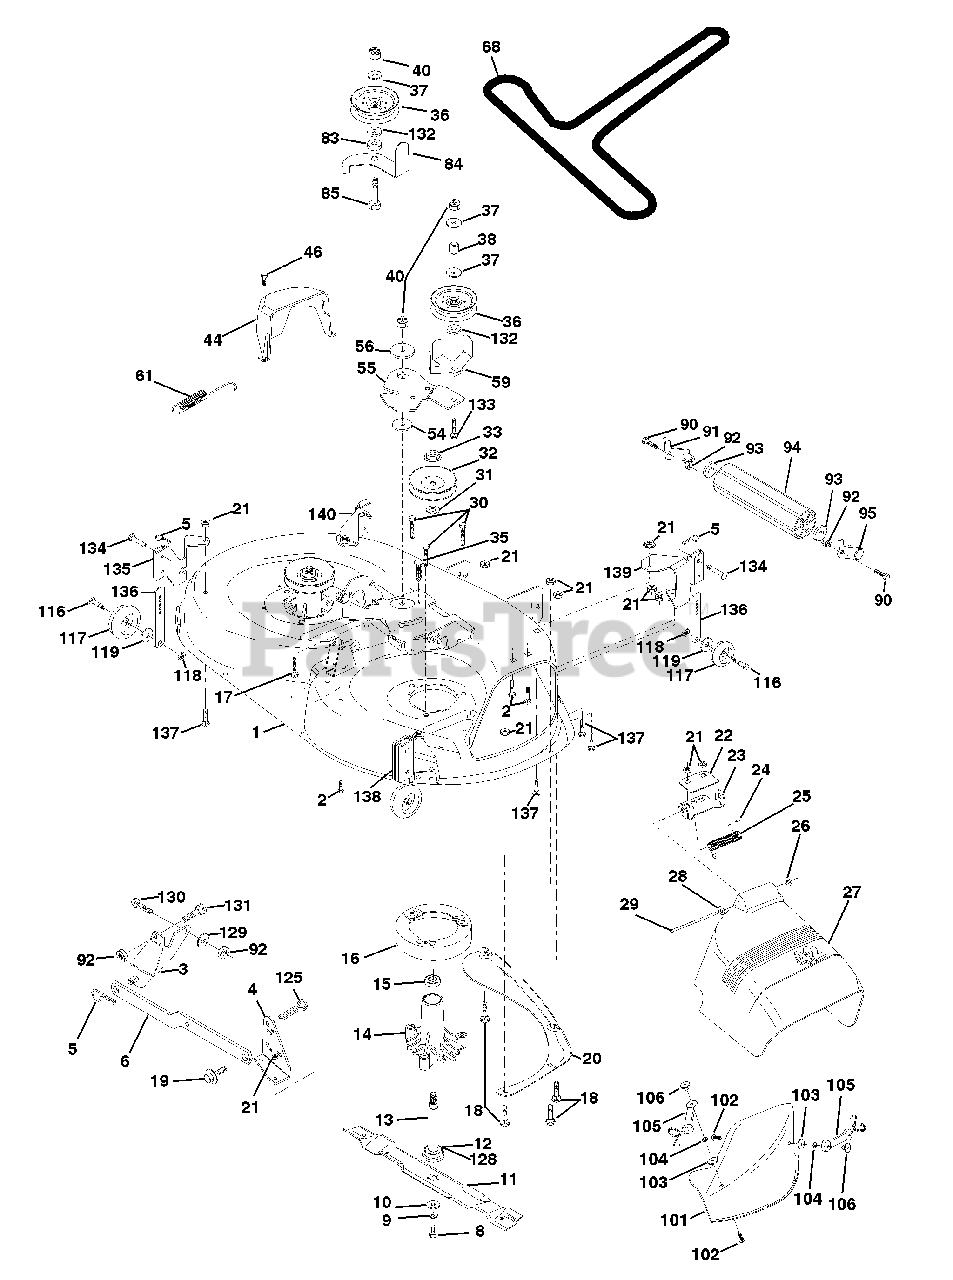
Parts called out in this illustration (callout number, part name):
1	Deck Weldment Mower
2	Bolt Rdhd Sqnk 5/16-18unc X3/4
3	Bracket Asm Fr Sway Bar 38/42
4	Bracket Asm Deck 42" sway Bar
5	Retainer Spring
6	Arm Suspension Rear
8	Bolt 3/8-24x1 25 Gr8 Patched
9	Washer Lock Hvy 3/8 Unplated
10	Washer Hard Blade Mower Vented
11	Blade Mower Mulching 42"
12	Bearing Ball #6204 (Mandrel)
13	Shaft Asm W/lower Bearing
14	Housing Mandrel Vented (machd)
15	Bearing Ball Mandrel
16	Stripper Round Mower
17	Bolt Rdhd Sqnk 3/8-16 X 2-1/4
18	Bolt Carr 5/16-18 X 5/8
19	Bolt Shoulder
20	Baffle Vortex 42
21	Nut Crown Lock 5/16-18
22	Stiffener Bracket 42" deck
23	Bracket Deflector Mower 42"
24	Cap Sleeve 80 x 112 Blk Mower
25	Spring Torsion Deflector 2 52
26	Nut Push Phos & Oil
27	Shield Deflector Mower 42" Blk
28	Washer 11/32 X 5/8 X 16 Ga
29	Rod Hinge 42" 6 75 Wlg
30	Screw Thdrol Washer Head
31	Washer Spacer Mower Vented
32	Pulley Mandrel 42"
33	Nut 9/16 top Lock Flng Cntr
35	Fastner Christmas Tree
36	Pulley Idler Flat 3 060
37	Washer 13/32 X 13/16 X 16 Ga
38	Spacer Spring Stop Idler
40	Nut Lock 3/8-16 Unc
44	Guard Mandrel LH Black
46	Screw Thdrol 1/4-20x5/8
54	Washer Hardened
55	Arm Idler 42" mower LT/YT
56	Spacer Retainer Pm Mower
59	Guard, Belt
61	Spring Ext. Elect
68	V-Belt Mower
83	Washer Sintered
84	Keeper Belt Idler
85	Bolt Carriage 3/8-16 x 2-1/2 Gr.5
90	Bolt Fin Hex 3/8-16unc X 1
91	Bracket Asm Noseroller LH
92	Nut Lock Hex w/ins. 3/8-16 UNC
93	Washer 17/32 X 7/8 X 16 Ga
94	Roller Nose 38 & 42
95	Bracket Asm Noseroller RH
101	Cover Mulching 42" Blk
102	Screw
103	Washer #10
104	Washer Lock #10
105	Latch Asm Bagger
106	Nut Weld .327/.304 #10-24
116	Bolt Shld "A" 2.41 "B" 1.66
117	Wheel Gauge blk. 4.93
118	Nut Centerlock 3/8 - 16 UNC
119	Washer 3/8 x 7/8 x 14 Ga.
125	Cotter Pin
128	Washer Felt
129	Washer 13/32 x 13/16 x 12 Ga.
130	Bolt Fin Hex 3/8-16 UNC x 1 Gr. 5
131	Bolt RDHD SQNK 3/8-16 UNC x 1
132	Washer 13/32 x 1-3/8 x 3 Ga
133	Bolt Rd Hd 3/8-16 UNC x 2-3/4 Gr. 5
134	Pin Head Rivet
135	Bracket Asm. Whl Ga Rear LH 42"
136	Bar Pnt Adjusting Wheel Gauge
137	Bolt Carriage 5/16-18 x 5/8 Short
138	Bracket Asm. Whl Ga. Rear RH 42"
139	Bracket Asm. Whl Ga. Front RH 42"
140	Bracket Asm. Whl Ga. Front LH 42"
